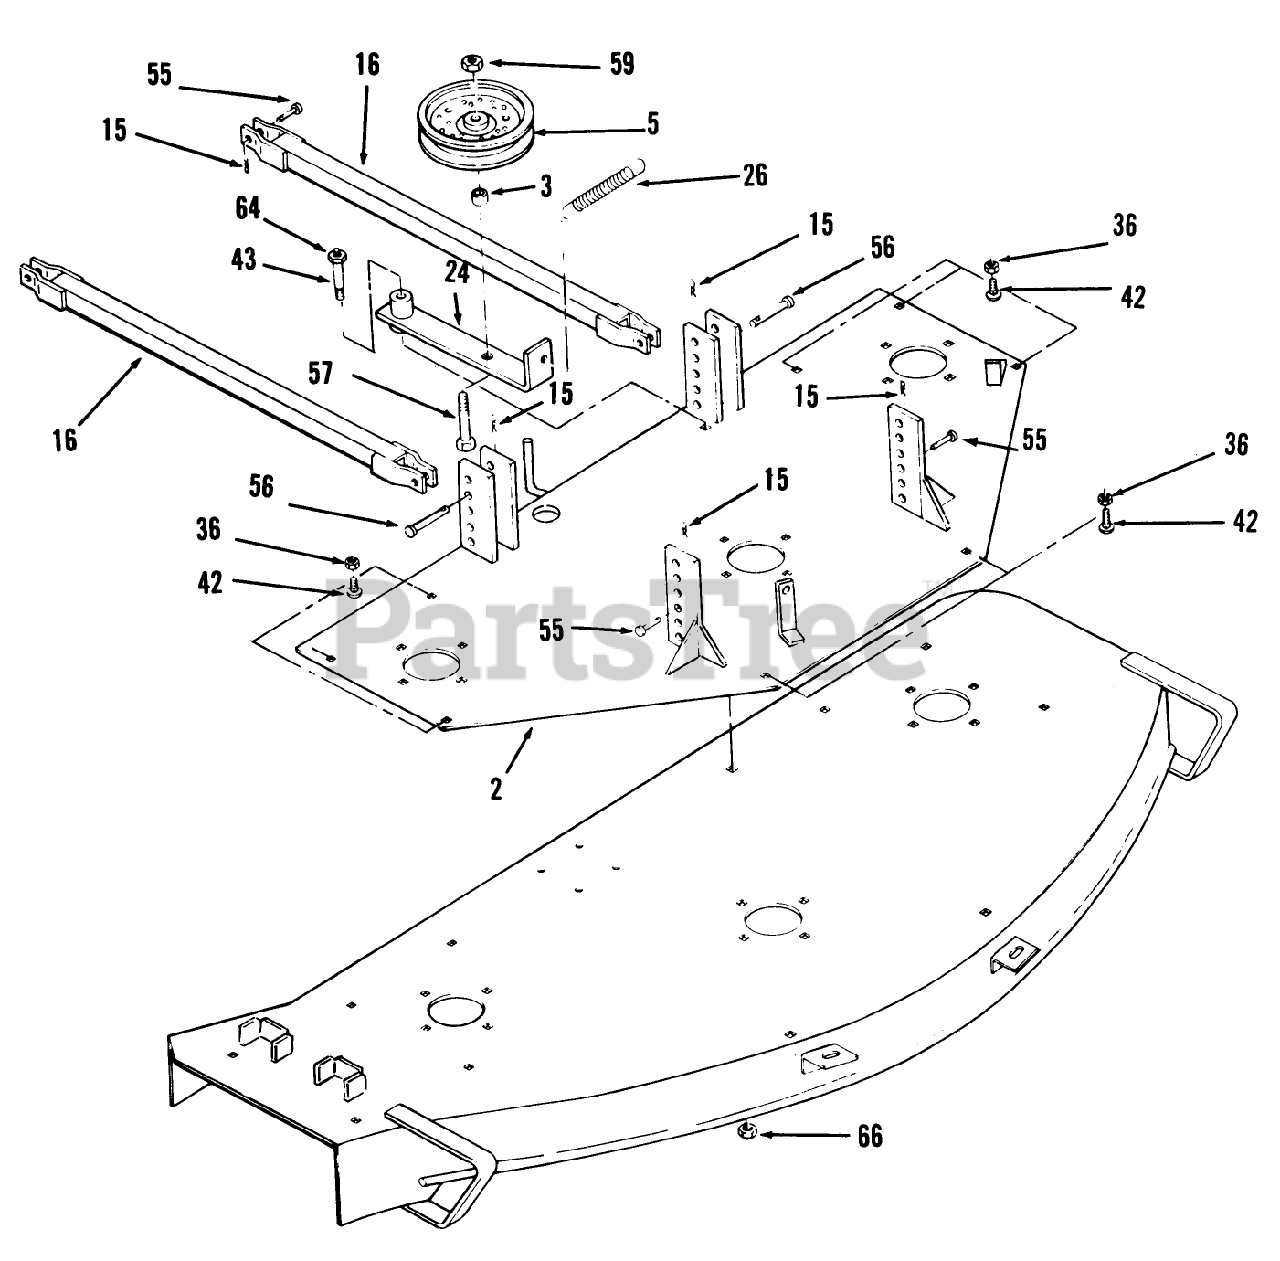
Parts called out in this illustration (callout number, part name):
2	ASS'Y-MWR DECK PL R
3	SPACER
5	PULLEY FLAT B
15	HAIRPIN
16	Bar-Stabilizer
24	ASS'Y-IDLER ARM R
26	SPRING-EXTENSION
36	NUT-LOCK, NI
42	BOLT-CARR
43	BOLT-SHOULDER
55	Clevis Pin 3/8 x 1 1/4
56	Clevis Pin 3/8 x 2-1/4
57	SCREW-HH
59	NUT-LOCK, NI
64	FITTING-GREASE, 90 DEG
66	NUT-LOCK, NI
